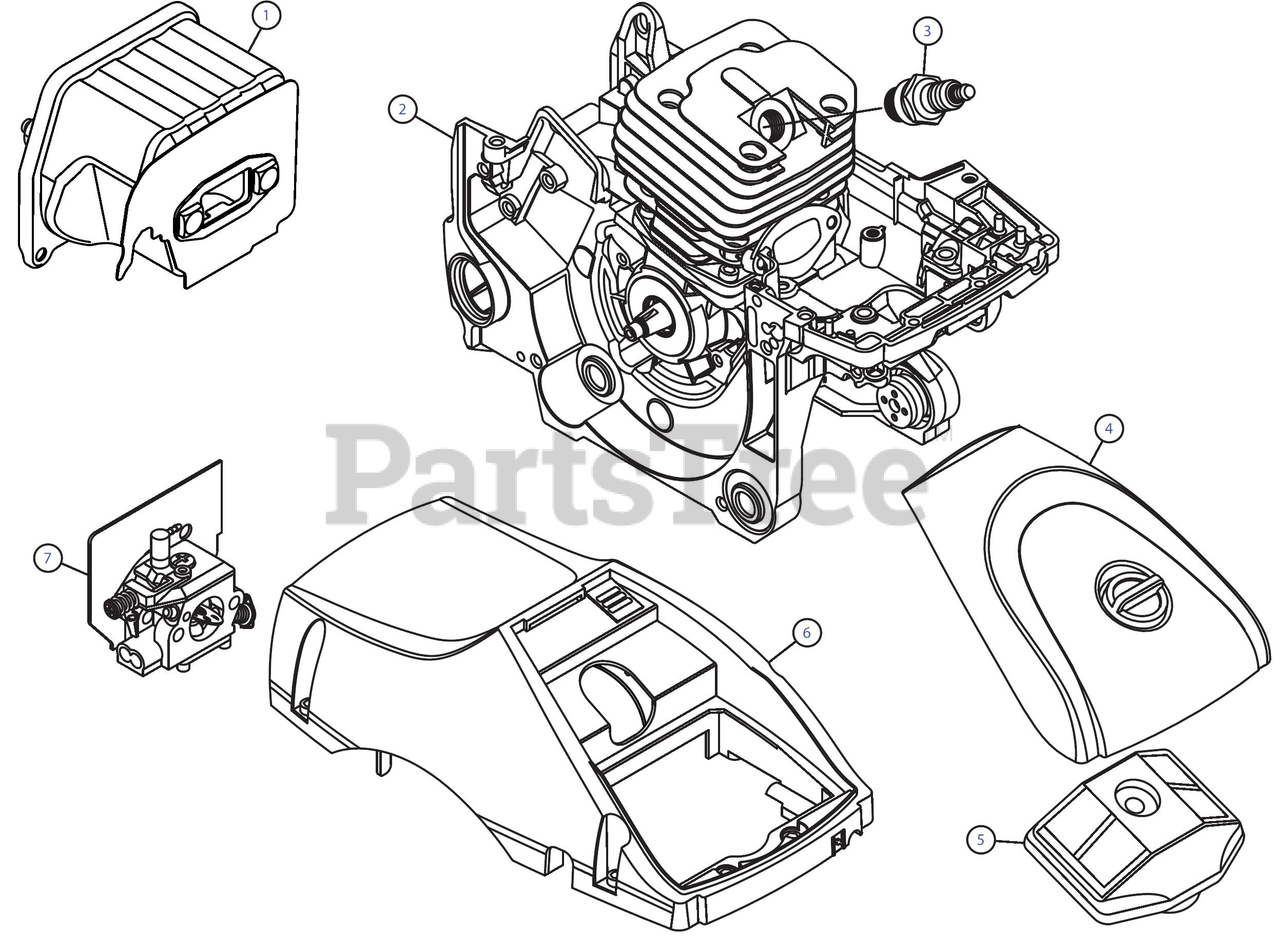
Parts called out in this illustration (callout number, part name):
1	Muffler Assembly
2	46cc Short Block Assembly
3	Spark Plug
4	Air Filter Cover Assembly
5	Air Filter
6	Cylinder Cover Assembly (with Plate and Screws (5))
7	Carburetor Assembly
